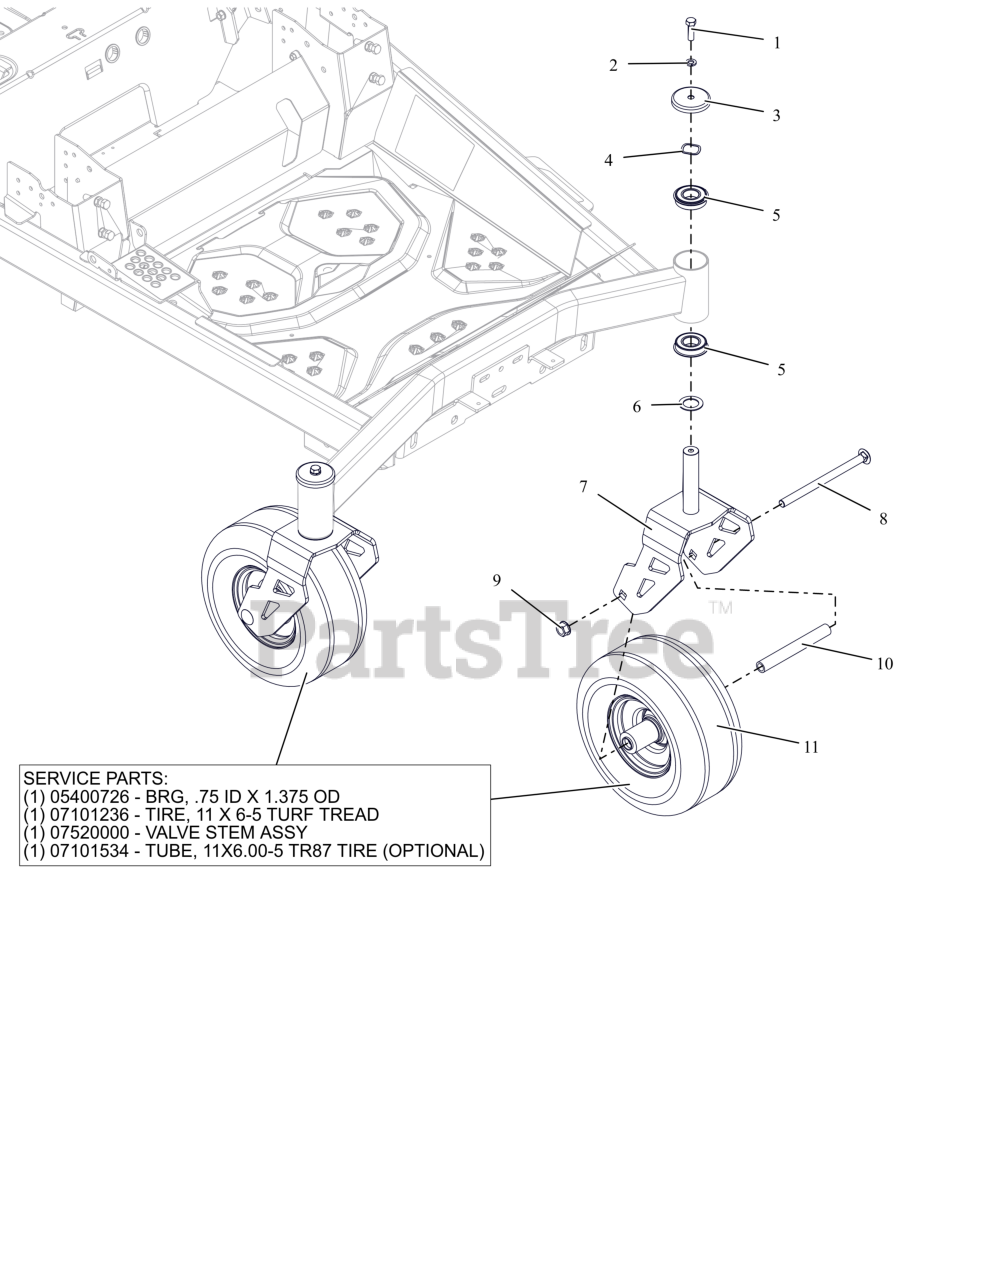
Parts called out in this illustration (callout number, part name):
1	BLT- HEX .38-16X1.25 G5 ZB500
2	WSHR-LK-REG .375X.094 ZB500
3	SHIELD- AXLE BEARING
4	WSHR-WAVE 1.0X1.25X.028 .145FH
5	BEARING, BALL -2.000 OD X 1.000 ID X .5625 W/RING
6	WSHR-HRD-THRS 1.007X1.542X.062
7	WMT-CASTER FOR-MY23
8	BLT-RHSN .50-13X7.50 G5 ZCC NS
9	NUT-LK-CTR-FLG .500-13 GG ZCC
10	SPACER, FRONT WHEEL (WIDE 6.0)
11	TIRE/WHEEL ASSY 11X6-5
11	BRG, .75 ID X 1.375 OD
11	TIRE, 11X6-5 Smooth
11	VALVE STEM ASS'Y
11	Tire Tube, 11/6.0-5
